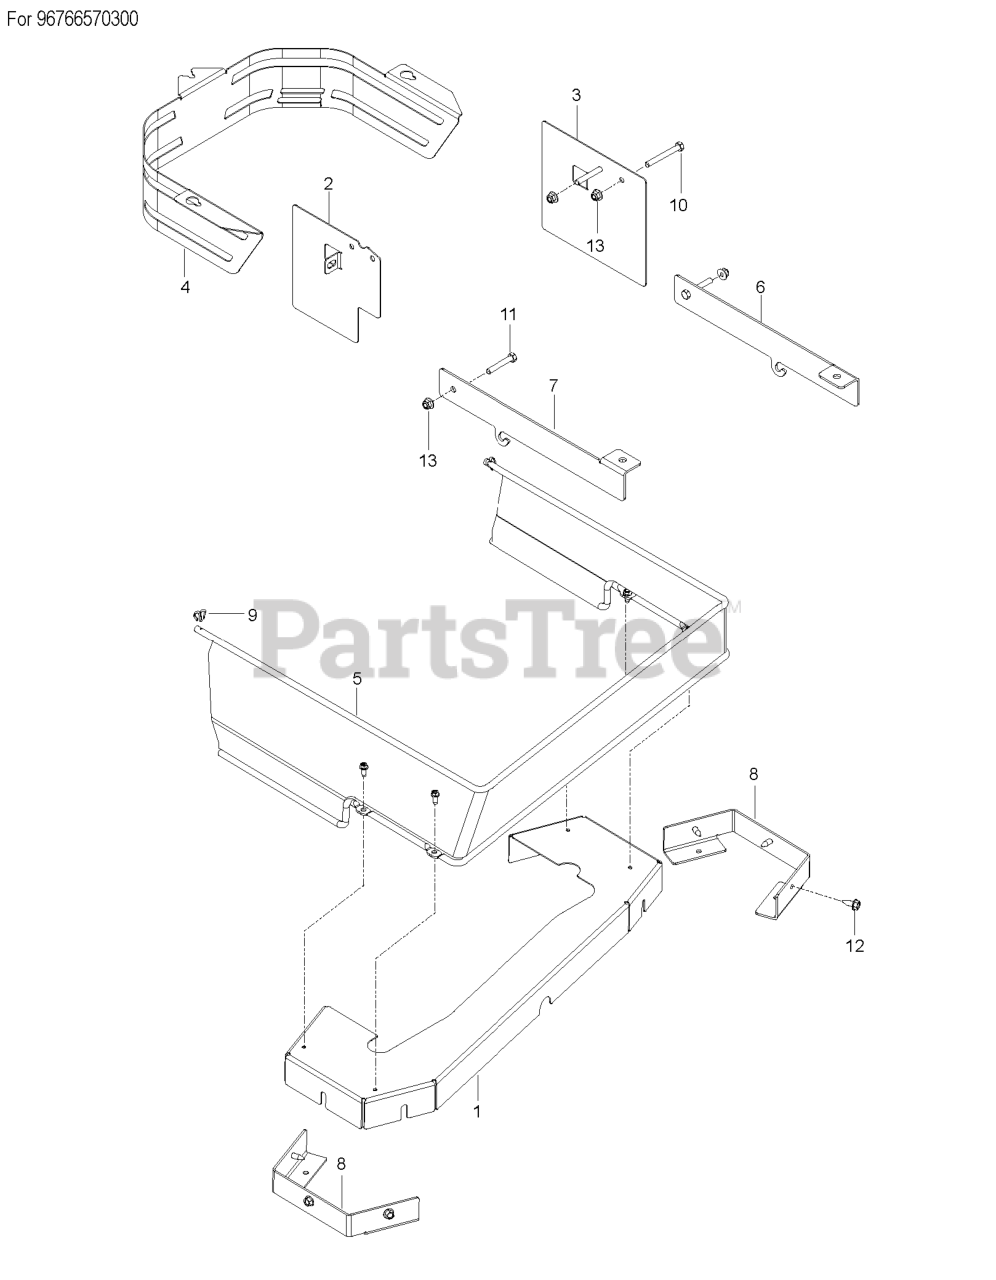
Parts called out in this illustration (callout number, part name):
1	GUARD FRONT GUARD, Z200 42" CC
2	GUARD RT SIDE WALL GUARD, Z200
3	GUARD LT SIDE WALL GUARD, Z200
4	GUARD REAR MUFFLER GUARD, Z200
5	GUARD CURTAIN GUARD ASSY, Z200
6	BRACKET LT HOOK, Z200 EURO GUA
7	BRACKET RT HOOK, Z200 EURO GUA
8	BRACKET PULLEY COVER DECK MOUN
9	RETAINER CLIP
10	BOLT.FIN HEX 5/16-18UNC X2 1/4
11	HCS 5/16-18 X 2 GR 5 ZD
12	SCREW
13	5/16-18 NYLOC FLANGE NUT
